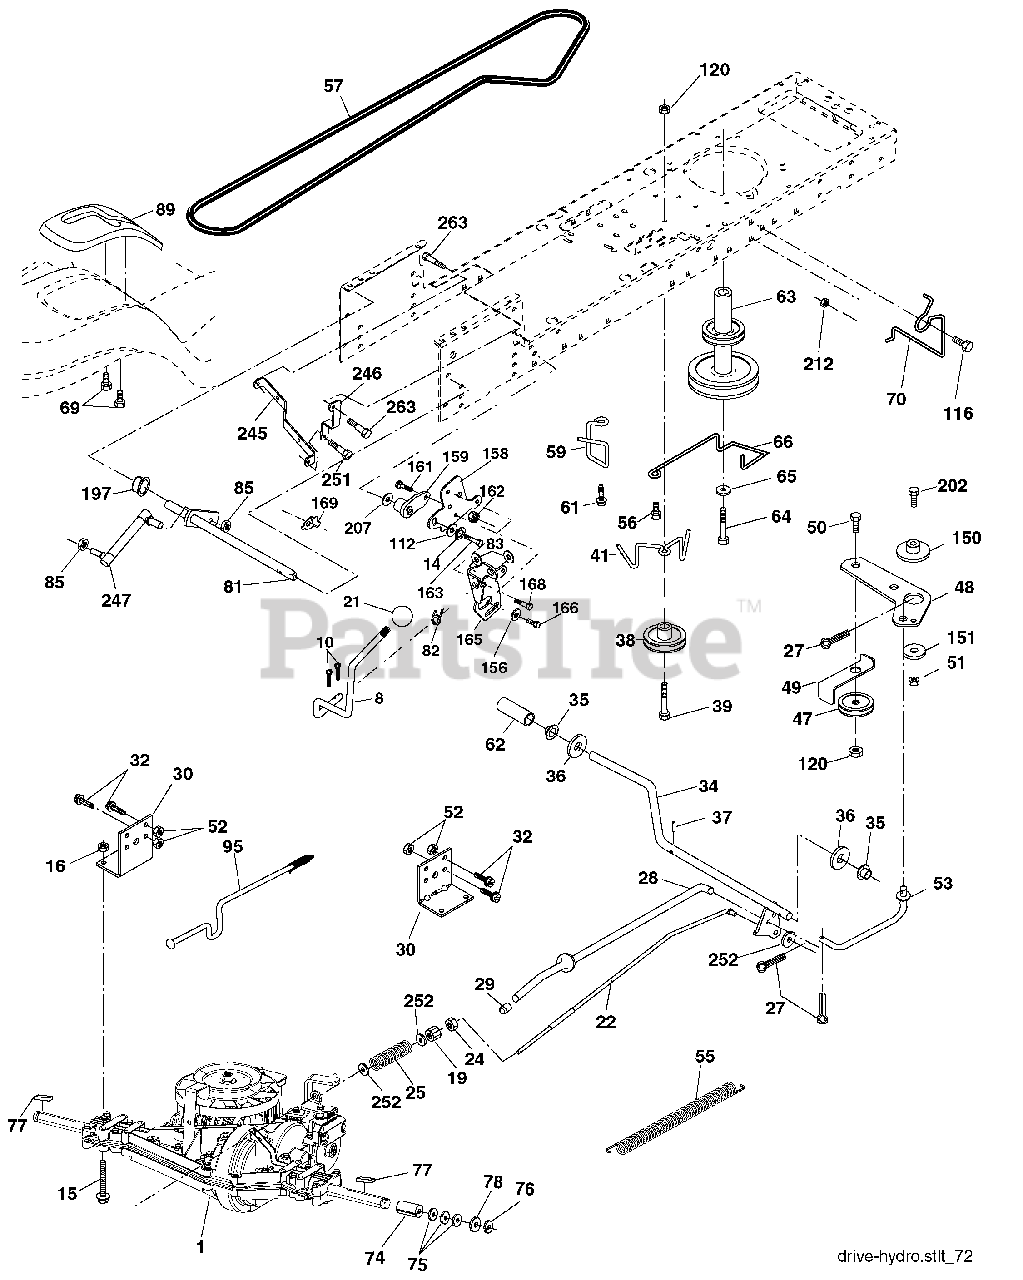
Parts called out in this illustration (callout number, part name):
8	Rod Shift
10	Pin Cotter 1/8 x 1 CAD
14	Washer Lock Hvy Helical
15	Bolt, Hex FLGHD 5/16-18 Gr. 5
16	Nut Lock Hex W/Ins 5/16-18 unc
19	Nut Lock Hex W/Wsh 3/8-16 unc
21	Knob, Round 1/2-13
22	Rod, Brake Hydro
24	Nut
25	Spring, Brake Rod
27	Pin Cotter 1/8 x 3/4 CAD.
28	Rod, Parking Brake
29	Cap, Parking Brake
30	Bracket, Transaxle
32	Bolt Hex Hd 5/16-18 unc x 3/4
34	Shaft, Foot Pedal
35	Bearing, Nylon
36	Washer
37	Pin, Roll
38	Pulley, Composite
39	Bolt Rdhd 3/8-16 unc x 2-3/4 Gr. 5
41	Keeper, Belt Idler
47	Pulley, Idler, V-Groove
48	Bellcrank Clutch Grnd Drv STL
49	Retainer, Belt
50	Bolt Carr Sh 3/8-16 x 1-1/2 Gr. 5
51	Nut Crownlock 3/8-16 unc
52	Nut Crownlock 5/16-18 unc
53	Link, Clutch
55	Spring, Return, Clutch
56	Screw 3/8-16 x 1-1/4
57	V-Belt, Ground Drive
59	Keeper, Center Span
61	Screw 3/8-16 x .875
62	Cover, Pedal
63	Pulley, Engine
64	Bolt Hex 7/16-20 x 4 x Gr. 5-1.5 Thr
65	Washer
66	Keeper Belt Engine
69	Screw Hex Wsh. Hi-Lo 1/4 x 1/2 unc
70	Guide Belt
74	Spacer, Axle
75	Washer 25/32 x 1-1/4 x 16 Ga.
76	E-Ring
77	Key, Square
78	Washer 25/32 x 1-5/8 x 16 Ga.
81	Shaft Asm. Cross Hydro
82	Spring Torsion T/A
83	Washer 17/32 x 3/4 x 16 Ga.
85	Nut Lock Center 1/4-28
89	Console, Shift
95	Disconnect Asm. Rod Bypass LTH
112	Washer 9/32 x 3/4 x 10 Ga.
116	Bolt RDHD SQNK 3/8-16 unc x 1
120	Nut Lock Flg 3/8-16 unc
150	Spacer Retainer
151	Washer 13/32 x 2 x 10 Ga.
156	Washer Srrted 5/16 ID x 1.125
158	Bracket Shift Mount
159	Hub Shift
161	Bolt Rdhd Sqnk 1/4-20 x 3/4 Gr. 5
162	Nut Crownlock 1/4-20 unc
163	Bolt Hex Fin 1/4-20 unc x 1 Gr. 5
165	Bracket Pivot Lever
166	Screw 5/16-18 x 5/8
168	Bolt Shoulder 5/16-18 x .561
169	Plate Fastening Lt
197	Nyliner Snap-In 5/8" ID
202	Bolt Carr Sh 3/8-16 x 1-3/4 Gr. 5
207	Washer Nyl 7/8 ID x .105
212	Nut Hex fl ange Lock
245	Strap Torque LH
246	Strap Torque RH
247	Link Shift Transaxle
251	Screw 5/16-18 x 1
252	Washer 13/32 x 1 x 16 Ga.
263	Screw Hex Wsh Thdr 3/8-16 x 3/4
